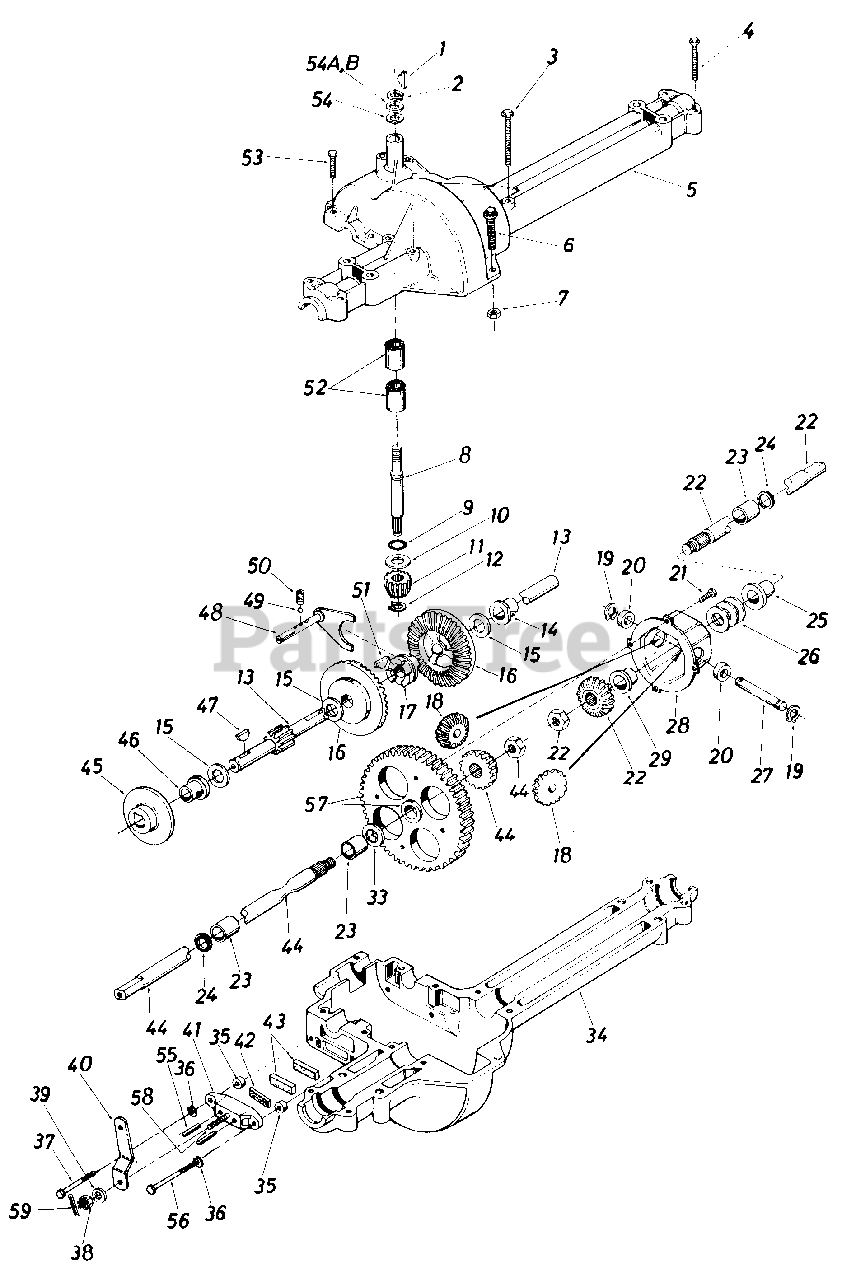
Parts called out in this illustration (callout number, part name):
1	#4 Hi-Pro Key 3/32 x 518" Dia.
2	Snap Ring .625" Shaft
3	Hex Bolt 1/4-20 x 1.75" Lg.
4	Hex Bolt 5/16-18 x 2.5"
5	Upper Housing
6	Hex Fl-Bolt 1/4-20 x .88" Lg.
7	Hex Nut 1/4-20 Thd.
8	Input Shaft
9	Square Seal 5/8" I.D.
10	Thrust Washer 5/8" I.D. x 1.25" O.D.
11	Pinion Input 14T
12	Retaining Ring 7116" Ext.
13	Drive Shaft
14	Flange Brg. 518" I.D. x 3/4" Lg.
15	Fl-Wash. (See Below)
15	Fl-Wash. 5/8" I.
16	Bevel Gear 42T
17	Clutch Collar
18	Miter Gear 15T (H.D.)
19	Snap Ring
20	Thrust Bearing 1/2" I.D. x 1.0" O.D.
21	Pan Head Scr. 1/4-20 x .50" Lg. w/Patch
22	Axle R.H. Ass'y.-Kit
23	Sleeve Bearing 3/4" I.D. x 1.0" Lg.
24	Oil Seal 3/4" I.D.
25	Flange Bearing 3/4" I.D. x 15/16" Lg.
26	Fl-Wash. .760" I.D. x 1.49" O.D.
27	Cross Shaft
28	Differential Housing Ass'y.
33	Fl-Wash. .760" I.D. x 1.49" O.D.
34	Lower Housing
35	Spacer .53" O.D. x 3/8" Lg.t
36	L-Wash. 1/4" I.D.t
37	Hex Bolt 1/4-20 x 1.50" Lg. (Grade 5)t
38	Castle Nut 5/16-24 Thd.t
39	Fl-Wash. .344" I.D. x .875" O D t
40	Actuating Armt
41	Brake Yoket
42	Puck Platet
43	Brake Puckt
44	Axle L.H. Ass'y.-Kit
45	Brake Disct
46	Flange Bearing 5/8" I.D. x 15/16" Lg.
47	Woodruff Key 3/16 x 5/8 HT
48	Shift Fork Ass'y.
49	Ball Detent .250" Dia.
50	Spring Detent
51	#9 Hi-Pro Key 3/16" x 3/4" Dia. HT
52	Needle Brg. 5/8" I.D. x 1/2" Lg.
53	Hex Bolt 1/4-20 x 1.00" Lg.
54	Fl-Wash. 5/8" I.D. x .030
54A	Fl-Wash. 5/8" I.D. x .040
54B	Fl-Wash. 5/8" I.D. x .040
55	Actuating Pin 5/16" Dia.t
56	Hex Bolt 1/4-20 x 2.50" Lg. (Grade 5)t
57	Differential Gear 72T Ass'y. w/Bearing
58	Sq. Hd. Bolt 5/16-24 Thd.t
59	Cotter Pin 3/32" Dia. x .50" Lg-t
